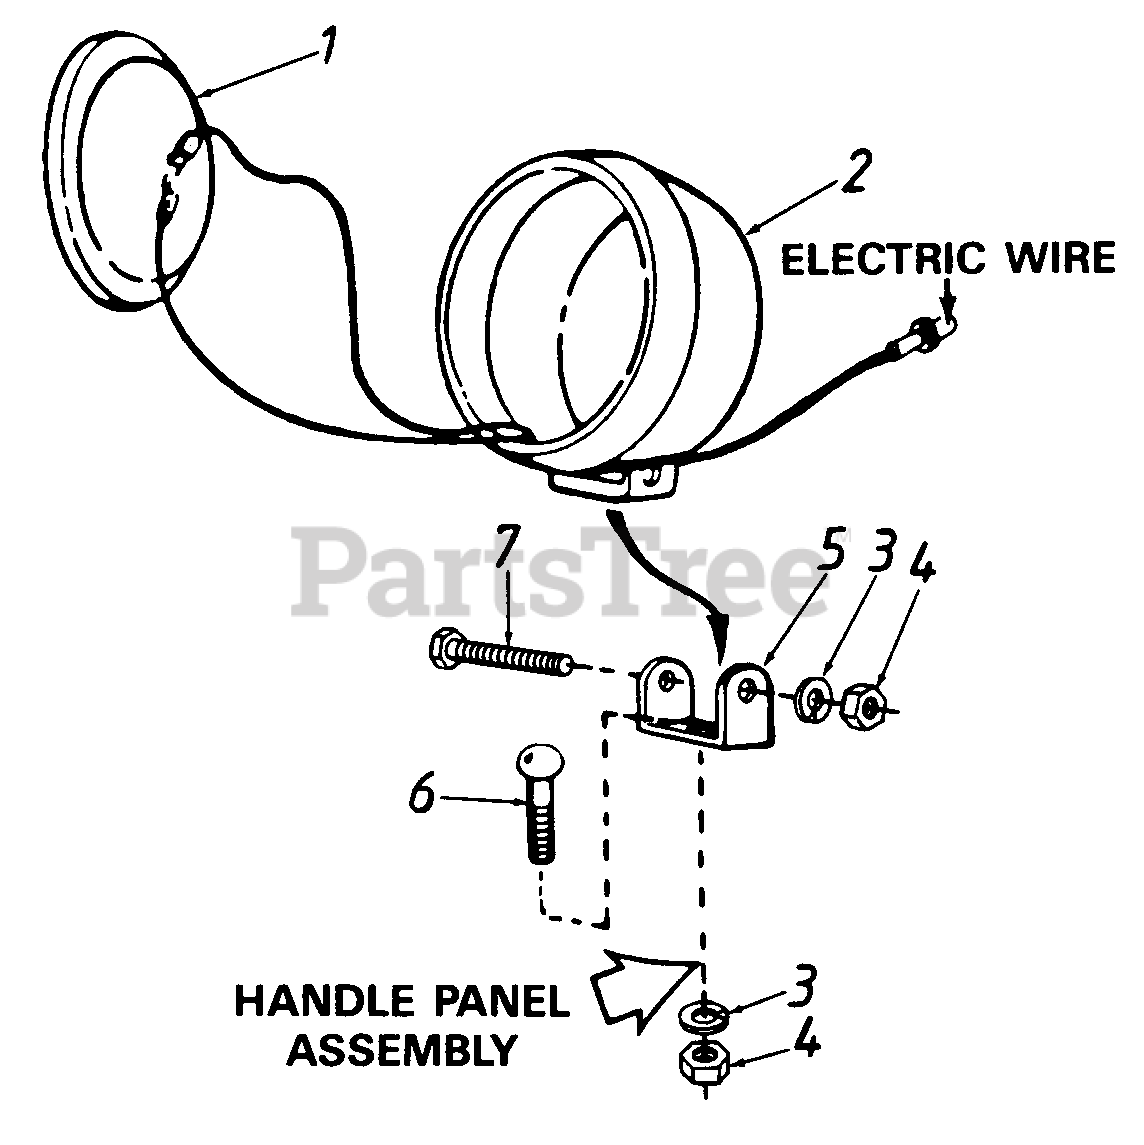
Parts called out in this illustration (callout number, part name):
1	Sealed Beam Headlight
2	Lamp Assembly
3	L.-Wash. 5/16" I.D.*
4	Hex Nut 5/16-18 Thd.*
5	Lamp Mounting Braket
6	Carriage Bolt 5/16-18 x 1" Lg,
7	Hex Bolt 5/16-18 x 2" Lg.*
